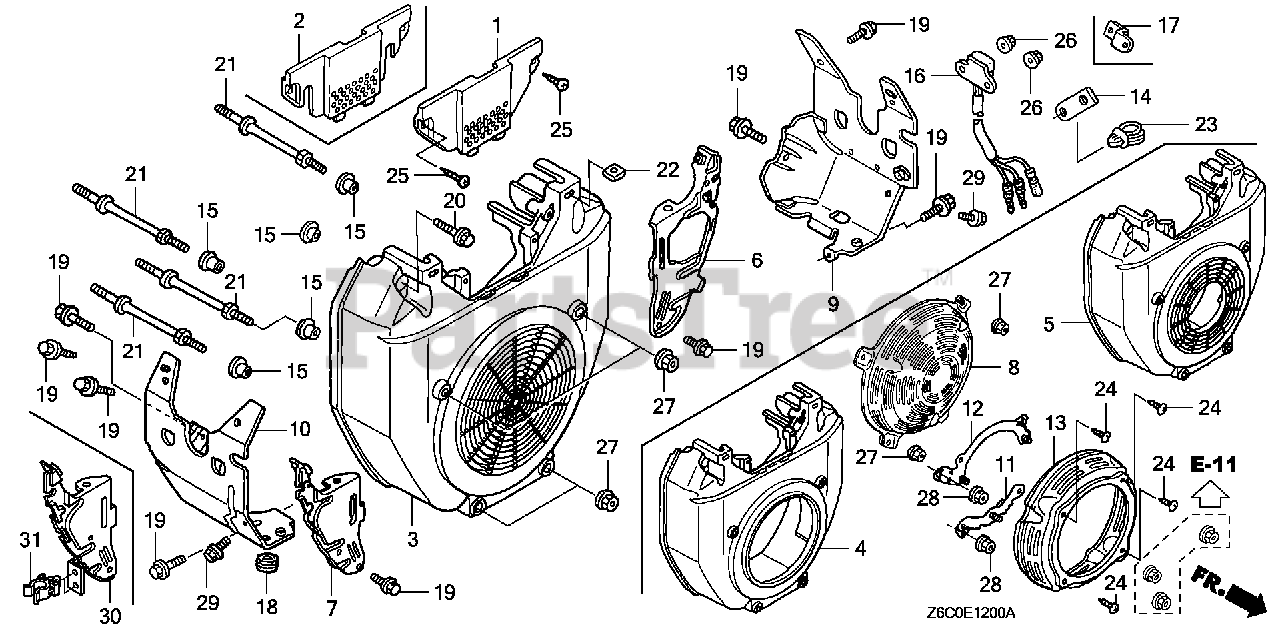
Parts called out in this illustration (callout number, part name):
4	COVER, FAN *R280* (RECOIL STARTER) (POWER RED)
6	PLATE, SIDE
7	PLATE, SIDE (R. SIDE)
9	SHROUD, R.
10	SHROUD, L.
15	COLLAR B, TAILLIGHT
18	RUBBER, RR. FENDER CUSHION
19	BOLT, FLANGE (6X12) (CT200)
20	BOLT, FLANGE (6X23)
21	BOLT, STUD (6X71)
22	NUT, SQUARE (5MM)
27	NUT, FLANGE (6MM)
29	BOLT, FLANGE (6X8)
